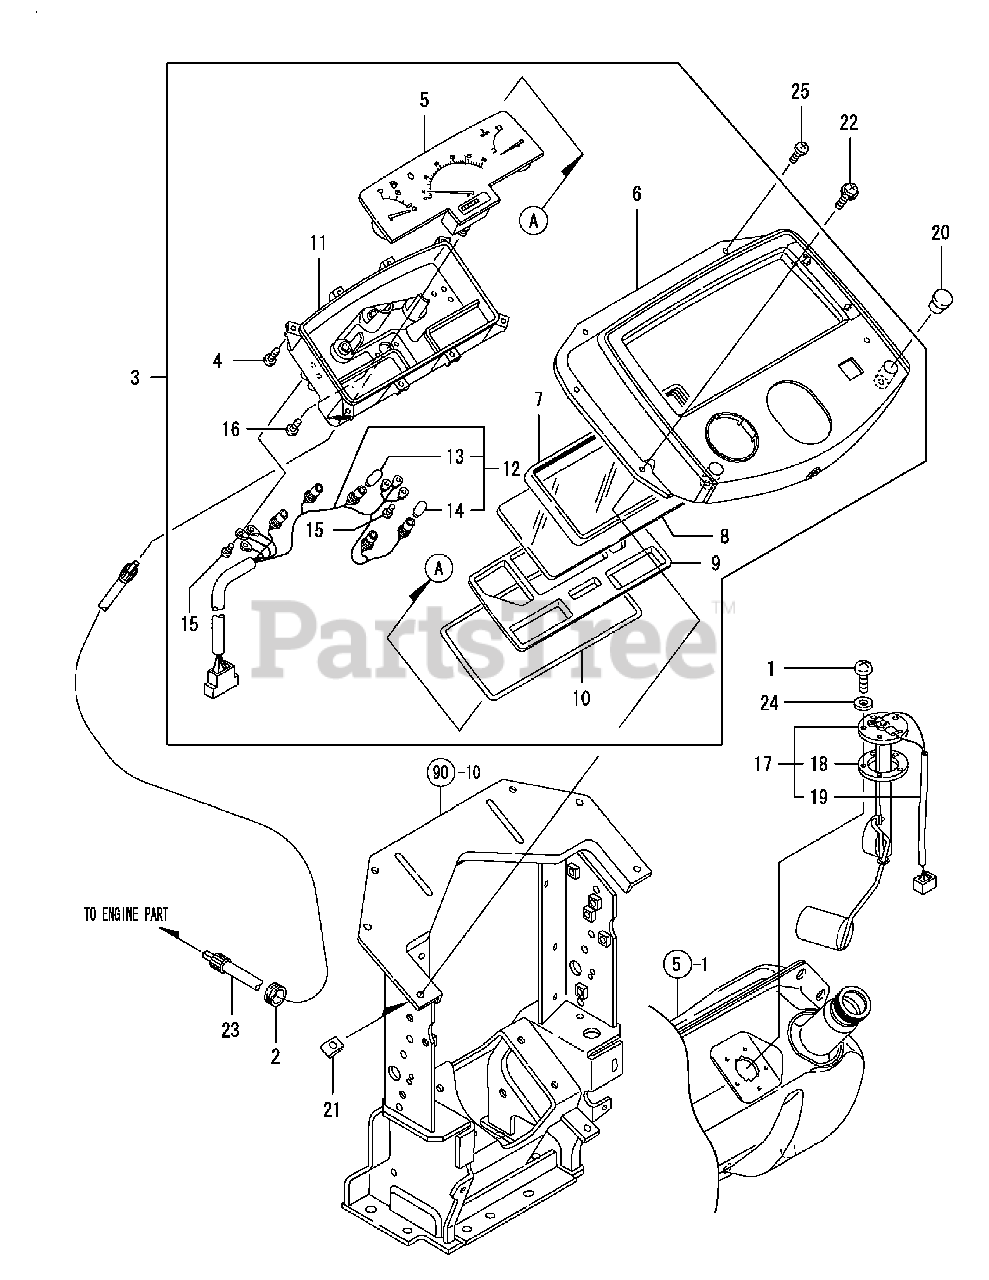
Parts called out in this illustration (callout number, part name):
2	GROMMET 25
3	PANEL,INSTRUMENT
4	SCREW
12	HARNESS,WIRING
17	SENDER ASSY, FUEL
22	SCREW 5X16
24	SEAL WASHER 5(BOLT)
25	SCREW M6,BINDING
